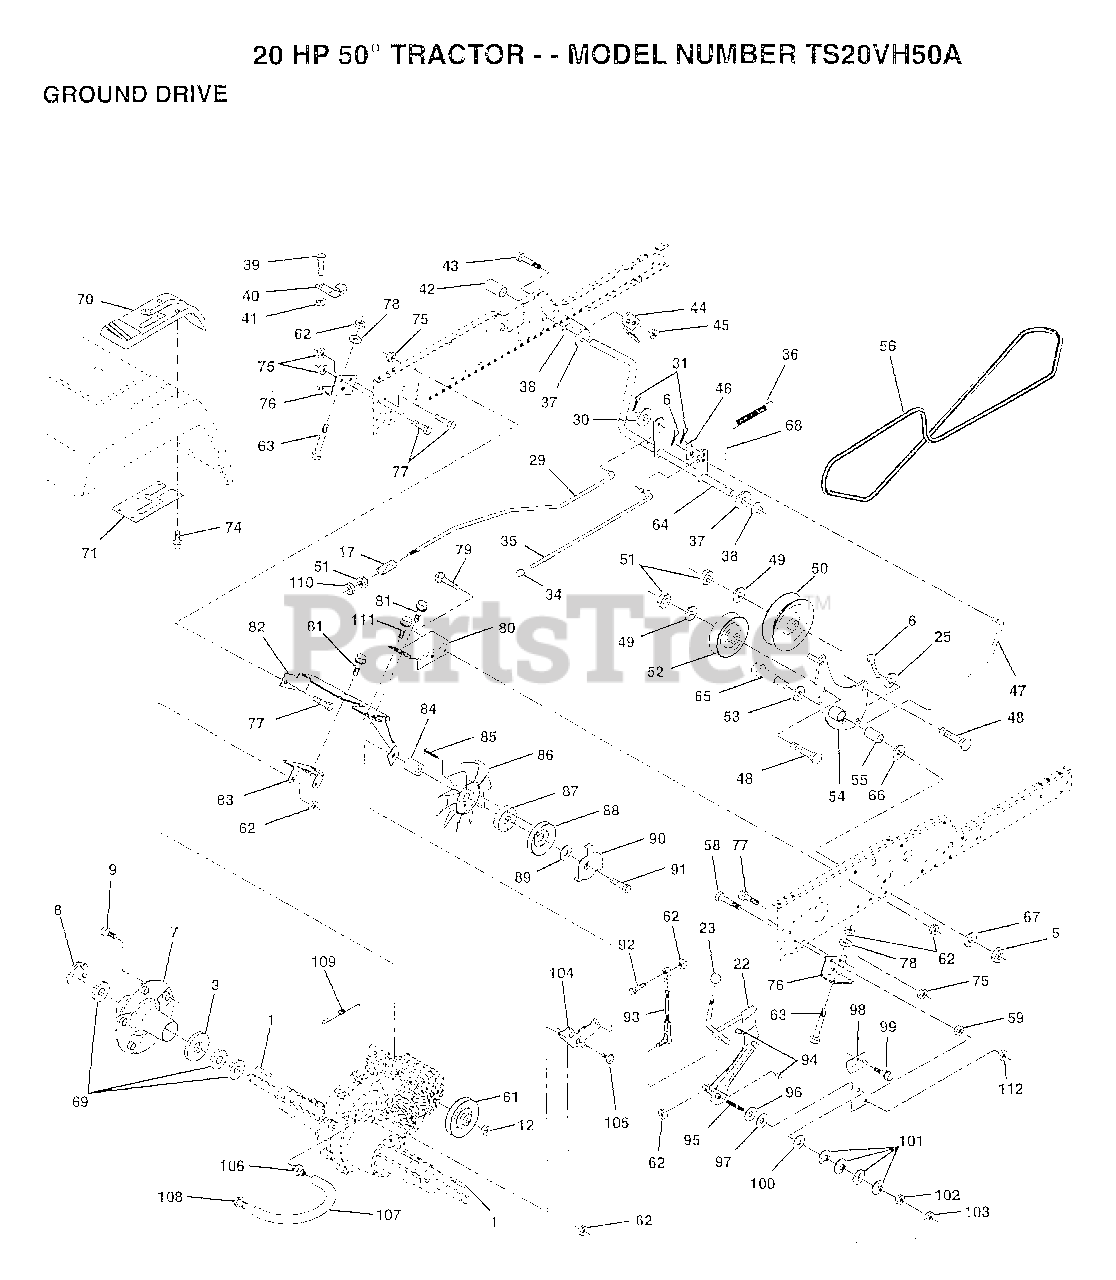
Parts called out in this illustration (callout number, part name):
1	KEY 1/4 X 2.5
3	WASHER T
6	COTTER PIN
7	HUB WHEEL ASM
8	E RING HYT
9	BOLT.HUB.WHL.REAR
17	SPRING ROD BRAKE
22	SHAFT ARM ASM
23	KNOB.DUCKHEAD.1/2
25	WASHER
29	ROD BRAKE
30	WASHER
34	PLUNGER CAP T
35	ROD BRAKE PART GT
37	WASHER
38	NYLINER T
39	SCREW
40	ACT-SWITCH T
42	PEDAL COVER T
43	BOLT LT
44	BRKT SWITCH GT
45	NUT
46	RETAINER SPRING
47	ROD.CLUTCH
48	BOLT
49	WASHER
50	FLAT IDLER PULLEY
51	NUT
52	PULLEY.IDLER.V.GR
53	WASHER T
54	ARM.ASM.IDLER.CLU
55	"LY, BEARING"
56	BELT-V 84.5
58	BOLT
59	NUT
61	PULLEY TRANSAXLE
62	NUT
63	BOLT FIN HEX 5/16
65	AXLE BOLT
66	WASHER.HARD.BLADE
67	WASHER
68	ROLL PIN STD
69	WASHER T
71	PLATE CONSOLE S
74	SCREW HEXWSH H-L
75	NUT.7/16
76	BRACKET TRAN VGTH
77	BOLT
78	WASHER
79	BOLT
80	BRACKET TORQUE RH
81	SCREW
83	STRAP TORQUE MID
84	SPACER
85	SCREW YTV
86	"FAN 7"" HYDRO"
87	ADAPTER FAN
89	WASHER
90	KEEPER BELT
91	SCREW.HXWSH.3/8
93	LINK ASM SHIFT
94	XMAS TREE FASTNER
95	SCREW SET 5/16
96	WASHER NICKEL PLT
97	BEARING THRUST
98	BRACKET SHIFT
99	SCREW LT
100	WASHER COMPRESSIN
101	WASHER
102	NUT HEX NYLOCK
103	JAM NUT TI
104	BRACKET IDLER
105	SCREW CRT
109	SPRING BRAKE
110	NUT
111	HINGE SCREW
112	NUT GTV
